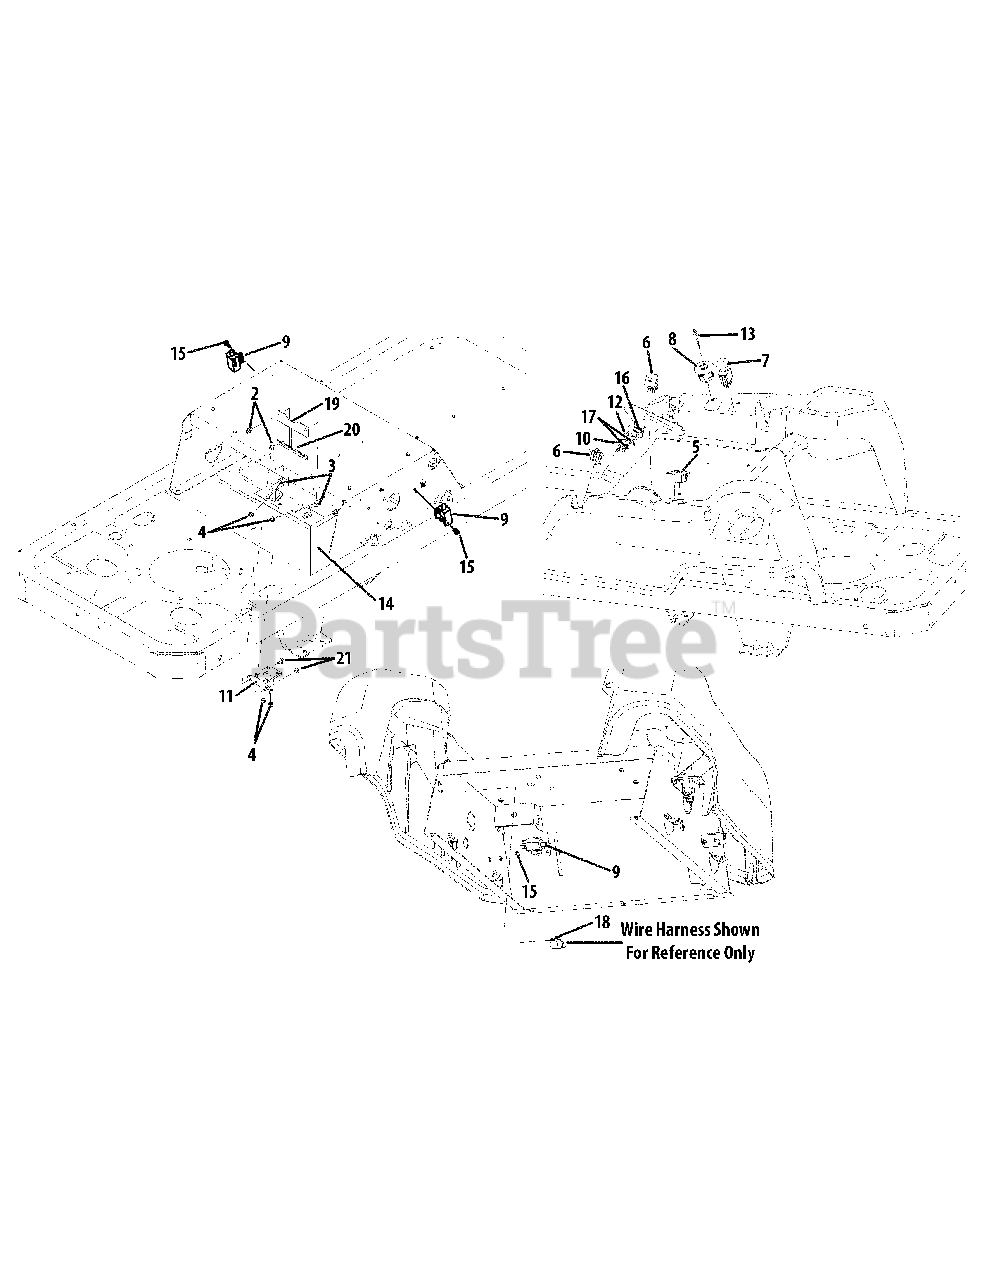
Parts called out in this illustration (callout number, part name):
1	Hex Screw, #8-18 x .5
2	Hex Screw, 1/4-20 x .5
3	Hex Screw, 1/4-20 x .75
4	Hex Nut, 1/4-20
5	Hour Meter
6	Double Pole - Neutral Switch
7	PTO Switch
8	Ignition Switch
9	Interlock Switch
10	Outer Seat Swing Switch
11	Solenoid
12	Inner Seat Spring Switch
13	Key
14	Battery, 235 CCA
15	Shoulder Screw, #10-32 x .500
16	Insulator Boss Plate
17	Insulator Plate
18	Cable Tie
20	Trim Strip
21	Hex Screw, 1/4-20 x .375
